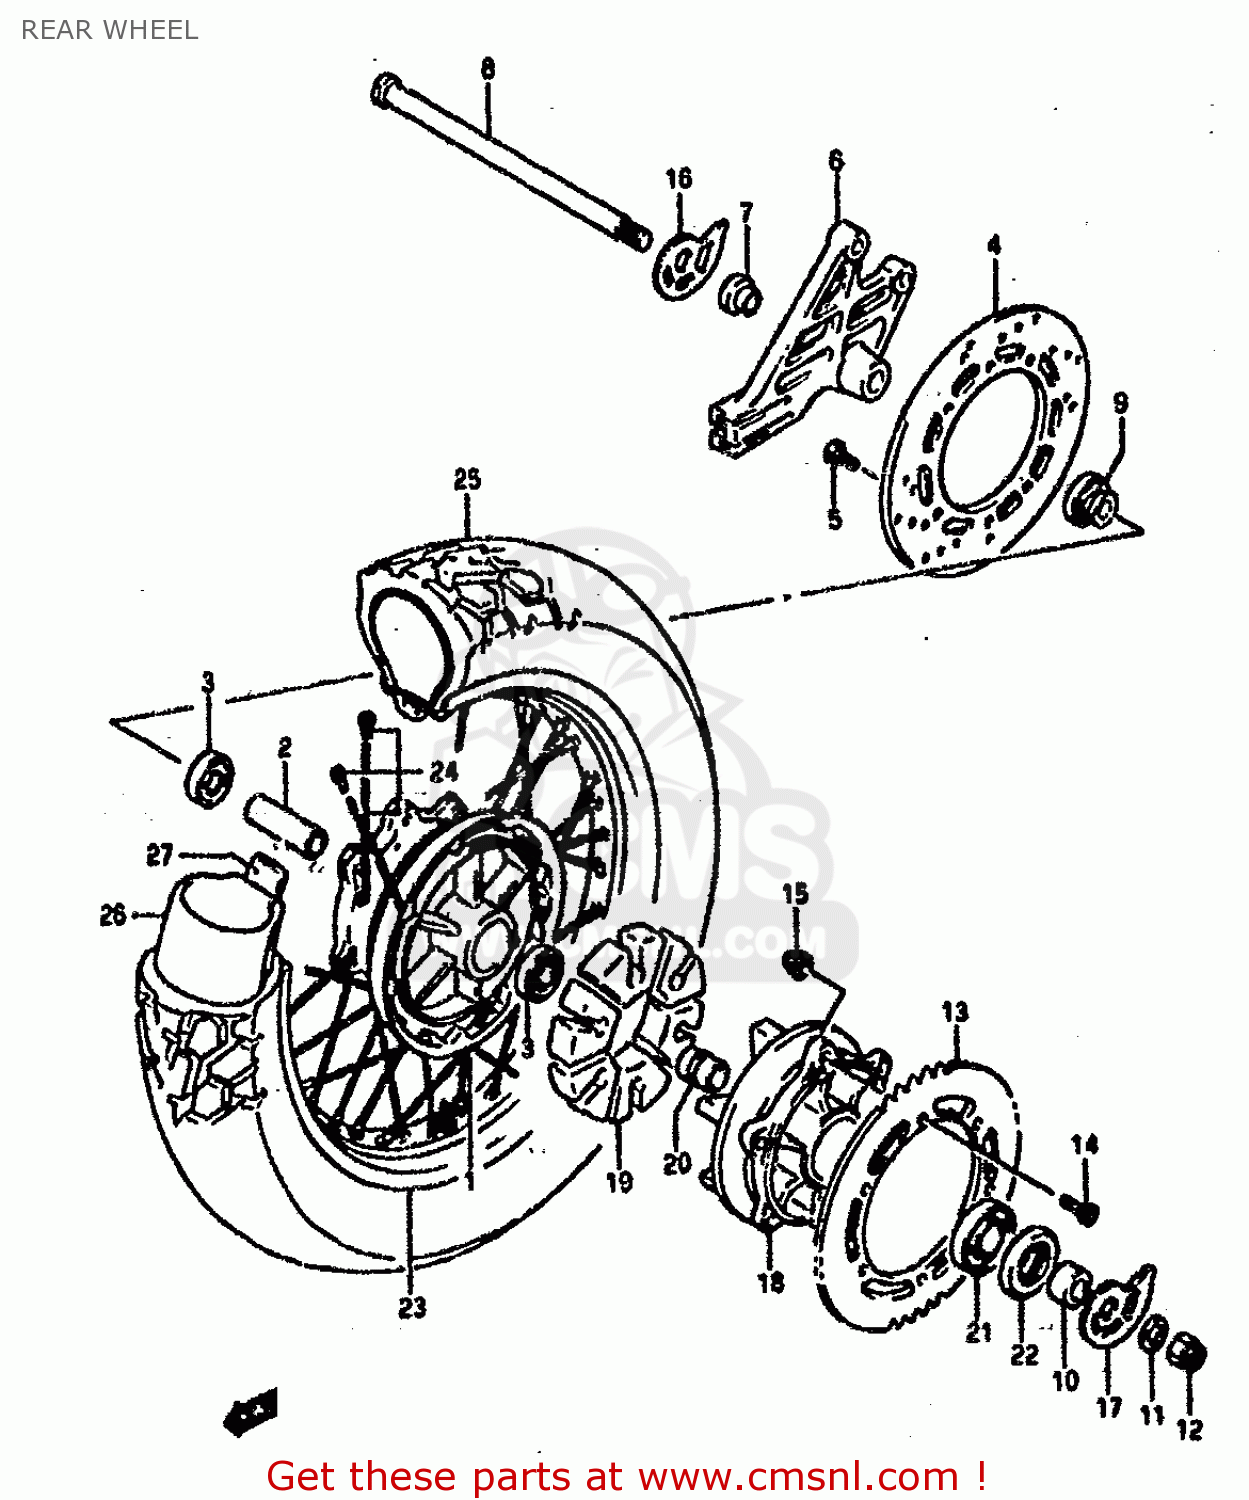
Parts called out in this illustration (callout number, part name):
1	HUB COMP,REAR WHEEL
2	SPACER(17.5X25X78)
3	BEARING
4	DISC,RR BRAKE
5	BOLT,BRAKE DISC
6	BRACKET,RR CALIPER
7	SPACER (17X21X10)
8	AXLE,RR
9	SPACER,RR AXLE,L
10	SPACER(17X33X22.4)
11	WASHER (17X30X3.2)
12	NUT
13	SPROCKET,REAR (NT:48)
14	BOLT(8X30.5)
15	NUT
16	ADJUSTER,CHAIN
17	PLATE,CHAIN ADJUSTER
18	DRUM,REAR SPROCKET
19	ABSORBER,RR HUB SHOCK
20	RETAINER,RR SPROCKET DRUM
21	BEARING(25X62X17)
22	SEAL,OIL(33X62X7)
23	RIM,REAR WHEEL (17XMT2)
24	SPOKE SET,RR
25	TIRE,REAR (130/80-17 65S)
26	TUBE ASSEMBLY,WHEEL,INNER
27	PROTECTOR,WHL INR TUBE
